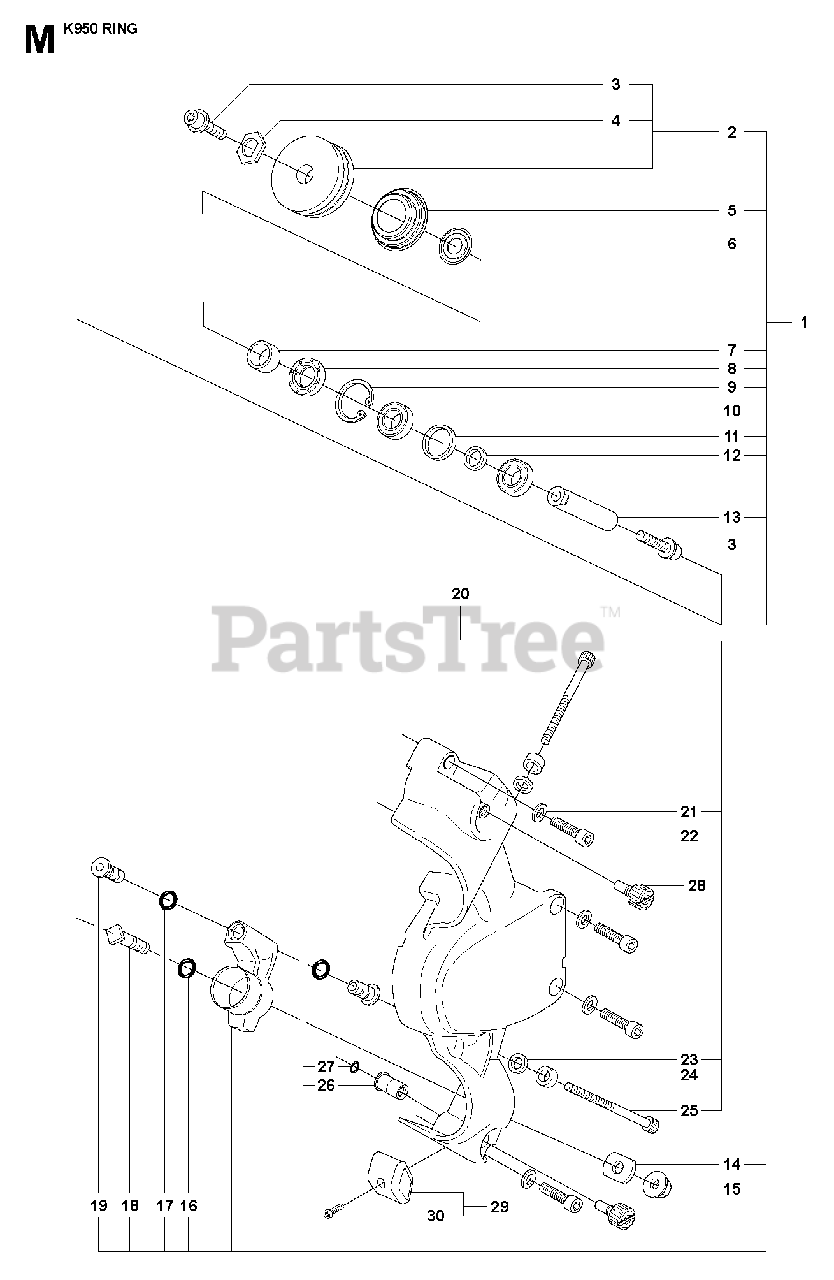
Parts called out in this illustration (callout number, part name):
1	LEVER ASSYIncl. 2, 5 - 19
2	SUPPORT ROLLERIncl. 3, 4
10	BALL BEARING
